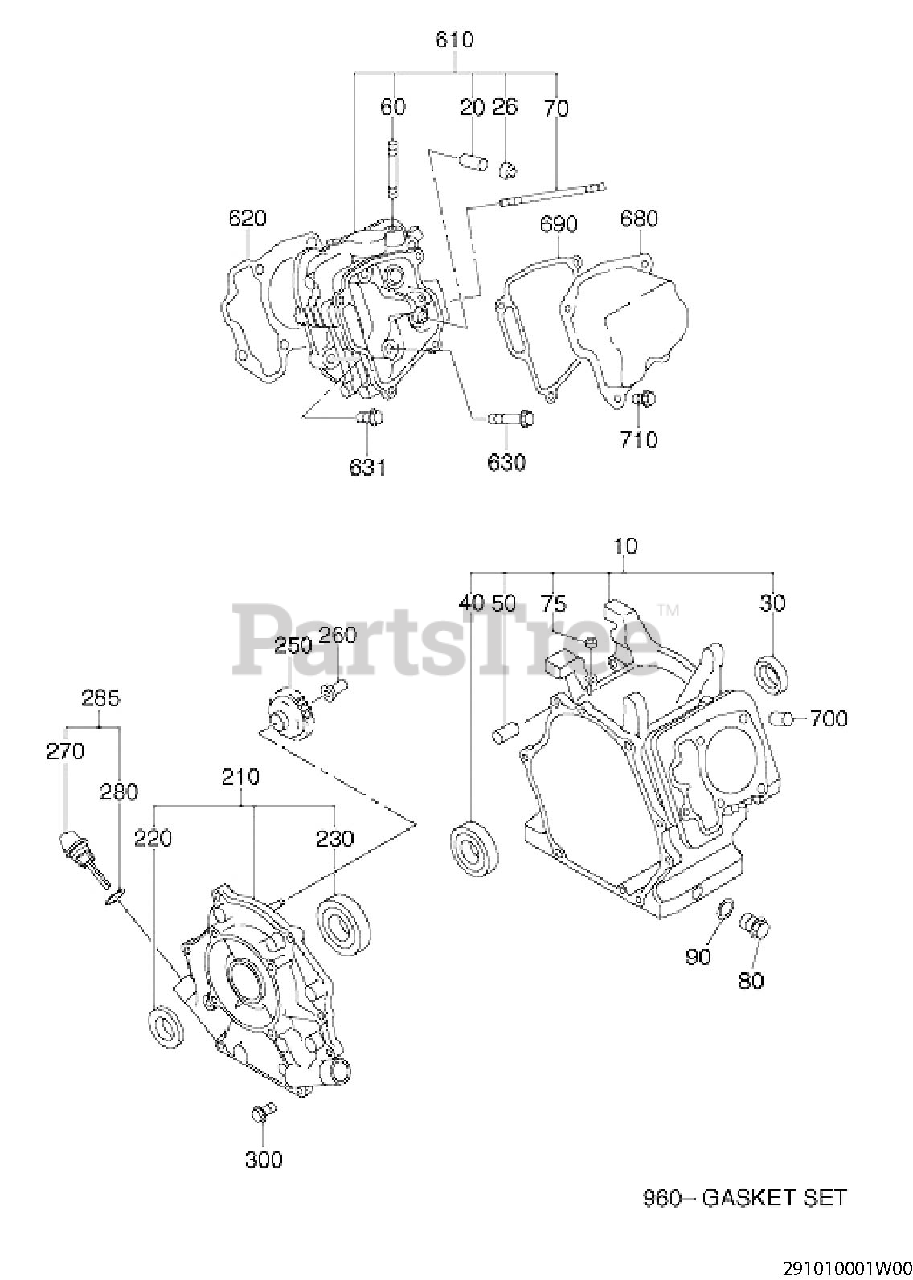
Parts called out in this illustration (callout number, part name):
20	VALVE GUIDE
26	STEM SEAL
30	OIL SEAL
40	BALL BEARING
50	PIPE KNOCK
60	STUD
70	STUD
75	OIL SEAL
80	PLUG
90	GASKET
210	MAIN BEARING COVER C
220	OIL SEAL
230	BALL BEARING
250	GOVERNOR GEAR CP
260	GOVERNOR SLEEVE
280	GASKET
285	OIL GAUGE AY
300	FLANGE BOLT
610	CYLINDER HEAD CP
620	GASKET (HEAD)
630	FLANGE BOLT
631	FLANGE BOLT
680	ROCKER COVER CP
690	GASKET(ROCKER COVER)
700	PIPE KNOCK
710	FLANGE BOLT
